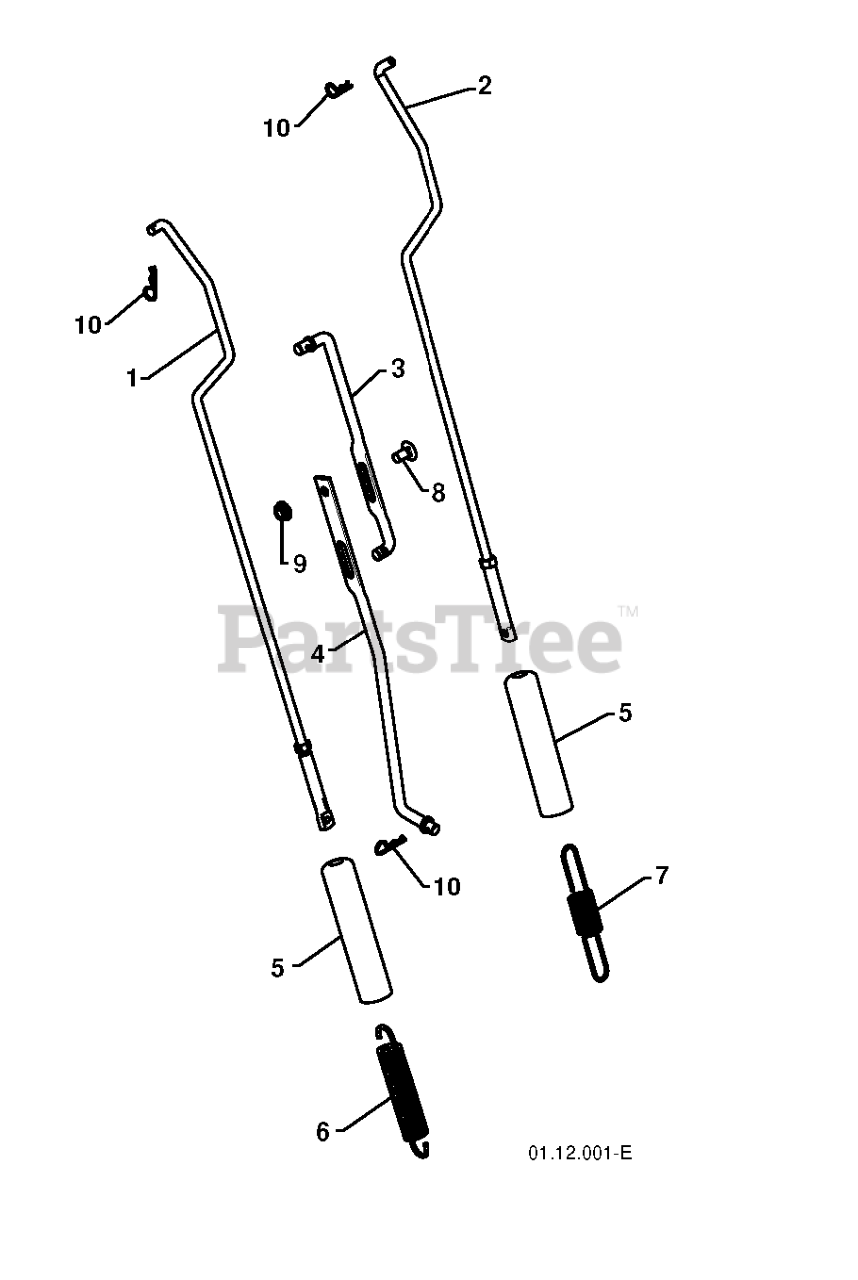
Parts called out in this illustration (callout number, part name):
1	ROD.ASM.IMPELLER
2	ROD.ASM.TRACTION
3	ROD, UPPER SPEED CONTROL
4	ROD, LOWER SPEED CONTROL.SNOW
5	SLEEVE, SPRING
6	SPRING, AUGER CONTROL
7	SPRING, TRACTION DRIVE
8	BOLT
9	NUT.FLANGE.5/16
10	SPRING RETAINER
